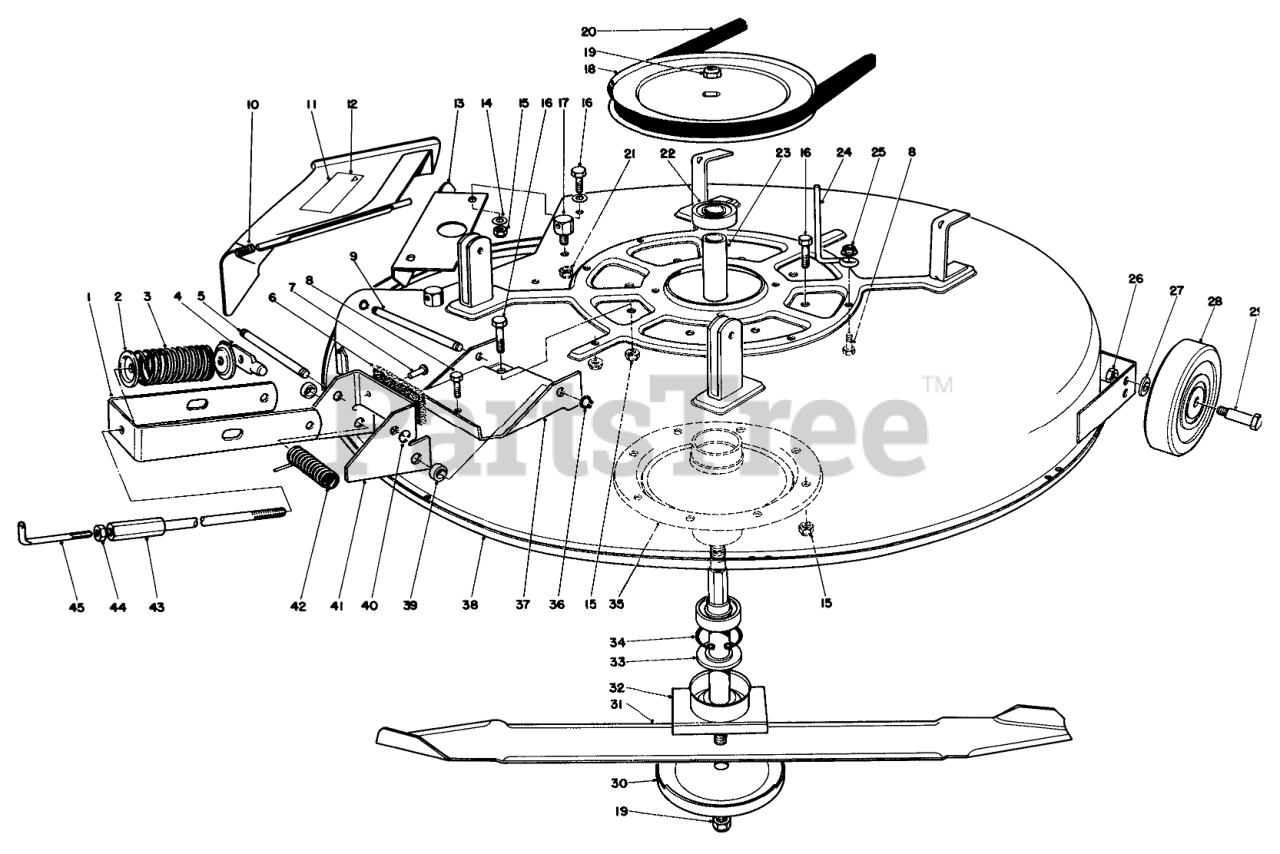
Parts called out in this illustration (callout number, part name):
1	Bracket-Engagement
2	RETAINER-SPR. TOP
3	SPRING-COMPRESSION
4	SHAFT-DECK ADJ.
5	Pin-Clevis
6	BRAKE PAD
7	RIVET .187 X 7/16 BRASS
8	SCREW-HH
9	CLEVIS PIN
10	SPRING
11	Deflector Assembly (Incl. Ref. #12)
12	Decal
13	Baffle Deck
14	WASHER-PLAIN
15	NUT-LOCK, NI
16	SCREW-HH
17	POST-PIVOT
18	PULLEY
20	V-BELT, DECK
21	NUT-LOCK, SIDE
22	BEARING-BALL
23	Spacer-Bearing
24	BELT GUIDE
25	NUT-LOCK, HHF
26	Nut
27	WASHER-FLAT
28	DECK WHEEL
30	Cup
31	Blade
32	SPINDLE SHAFT WA
33	SPACER-SPINDLE
34	RING-RETAINING
35	Spindle Body
36	RING-RETAINING
37	DECK ENGAGE CHANNEL R
38	Cutter Deck
39	DECK BRAKE SPACER
40	E-RING
41	Support Deck Brake Assembly (Incl. Ref. #6 & 7)
42	SPRING
43	ADJ HUB WA
44	NUT-JAM
45	ADJ. ROD
